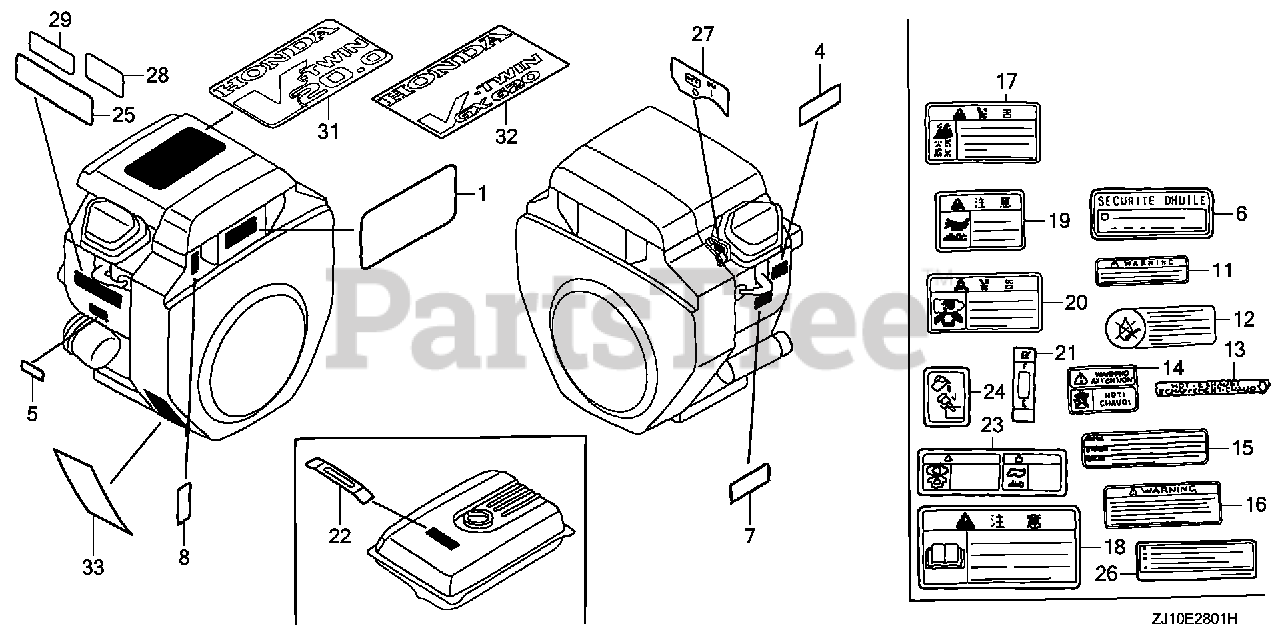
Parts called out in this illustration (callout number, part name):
1	MARK, EMBLEM (GX620)
4	LABEL, SPECIFICATION (GX620)
7	MARK, OIL ALERT (ENGLISH)
